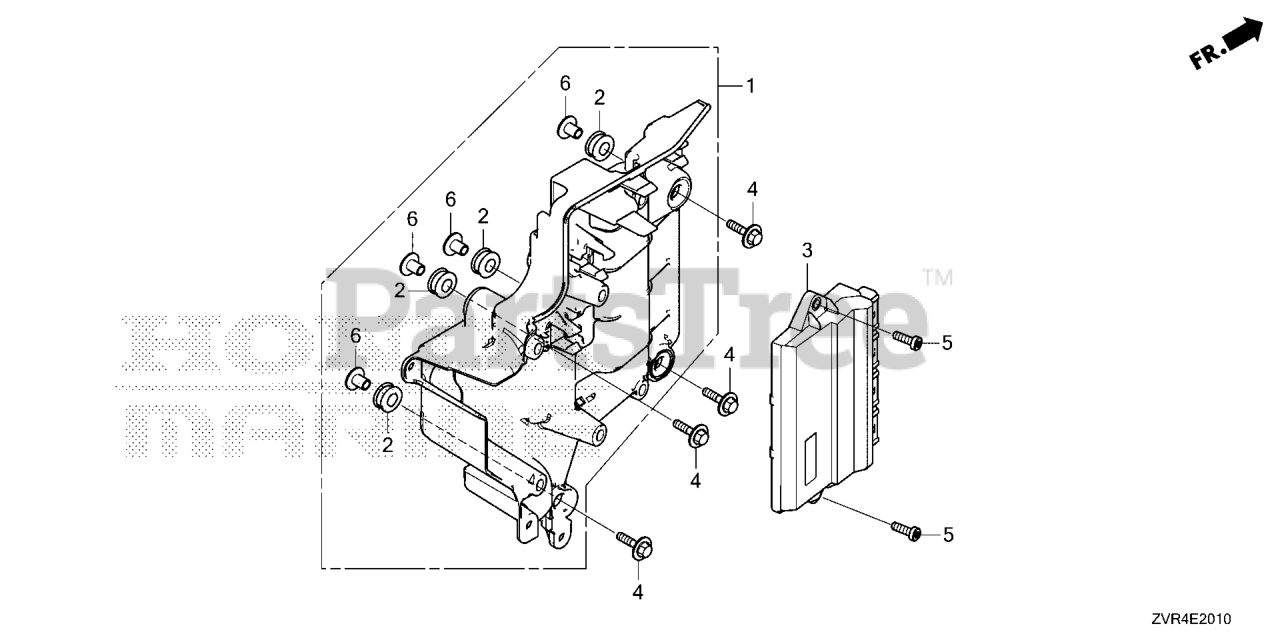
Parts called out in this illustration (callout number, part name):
1	CASE, ELEC PARTS
2	GROMMET, ELECTRONIC PARTS CASE
4	BOLT-WASHER (6X27)
5	BOLT, TORX (M6X20)
6	COLLAR (12X6.5)
